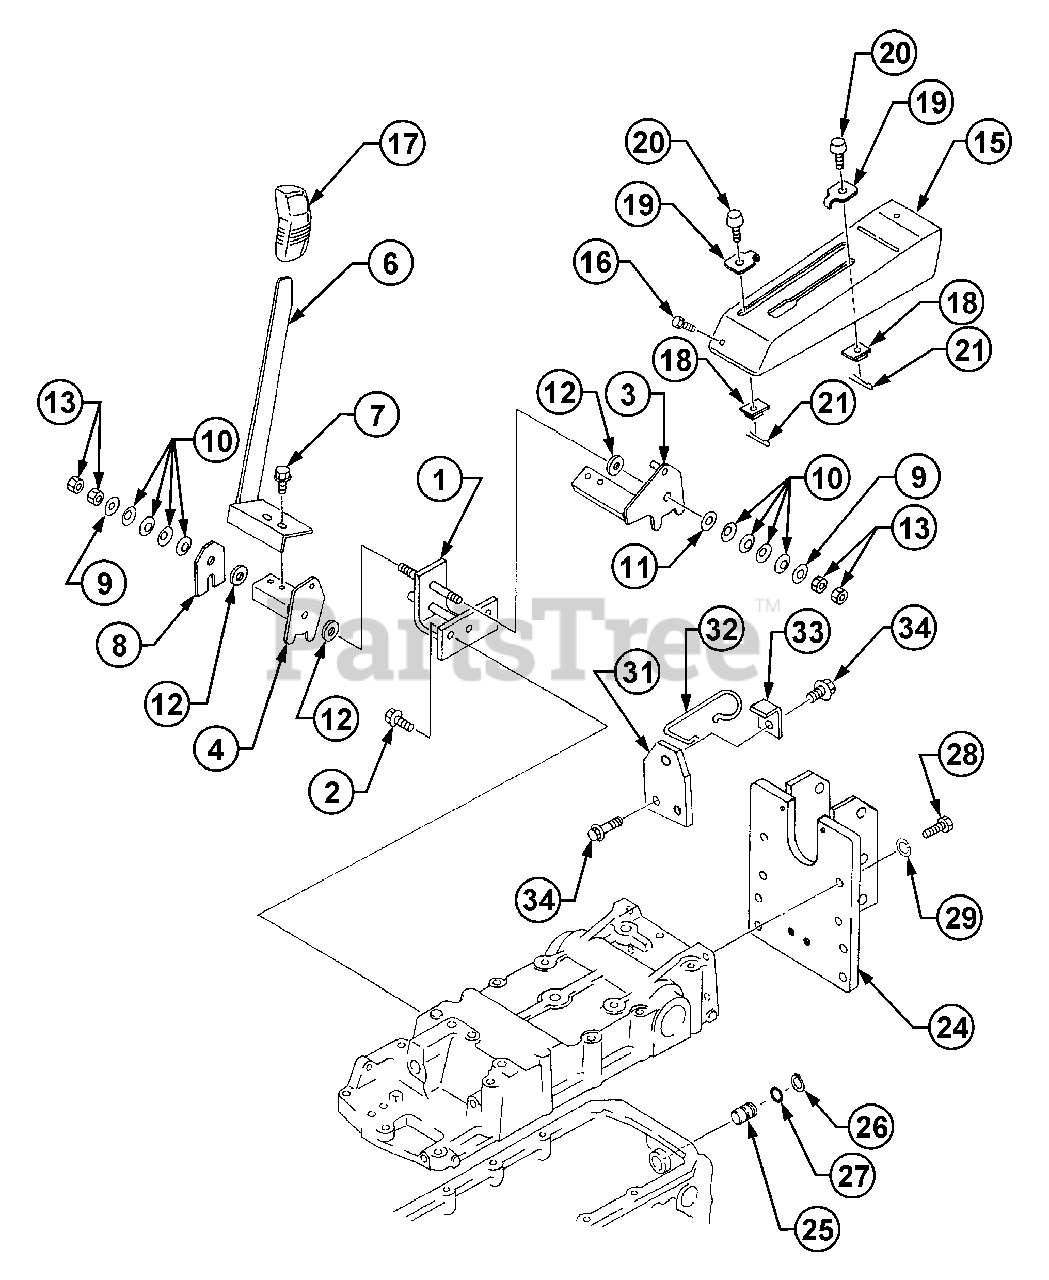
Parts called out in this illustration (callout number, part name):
2	Bolt, w/Washer
7	Bolt, w/Washer
10	Spring, Conical
11	Liner
12	Lining, Brake
18	Plate, Stopper
21	Pin, Split
29	Washer, Spring
31	Plate (Replaces MA-19613021AG0)
32	Hook Top Link
34	Bolt (Quantity used with MA-19613012AG0 Plate was three)
